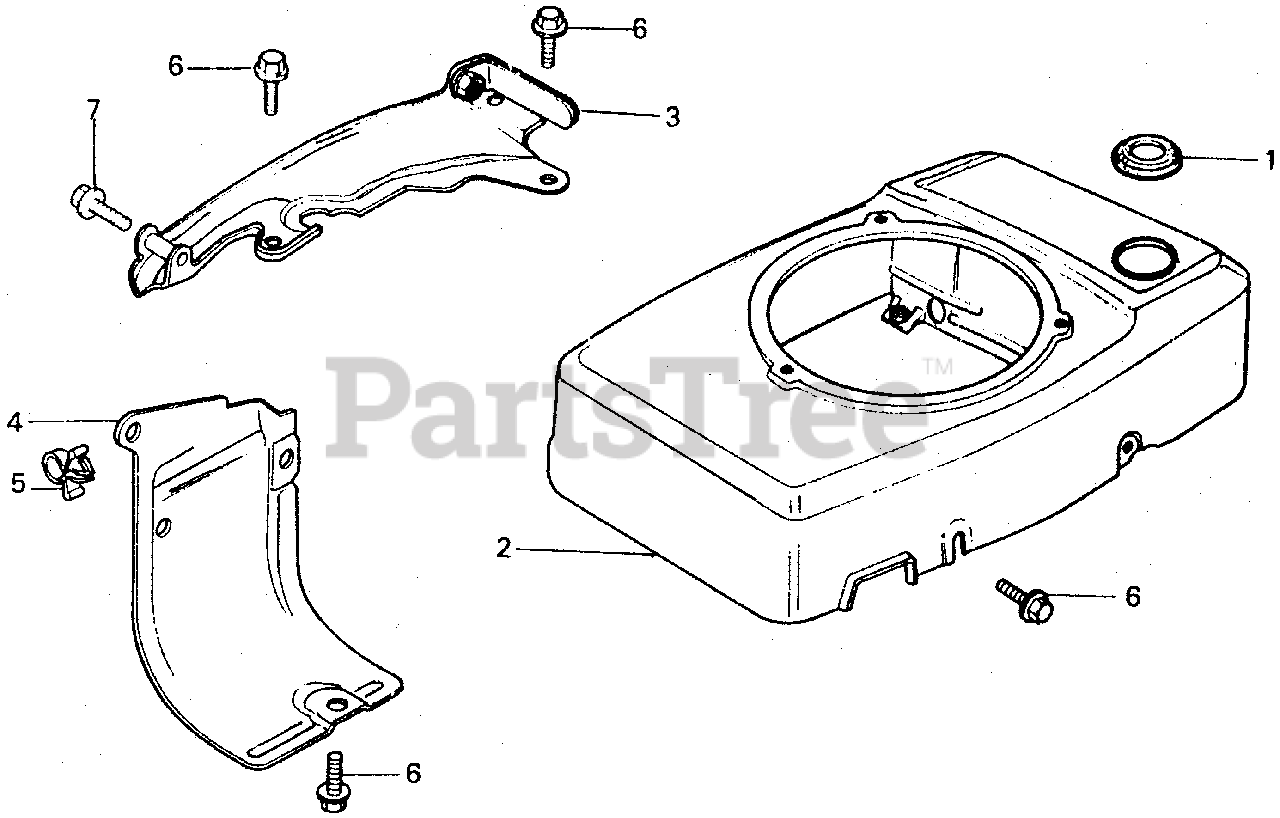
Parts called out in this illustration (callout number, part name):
1	SEAL, FILLER NECK
3	PLATE, SIDE
4	SHROUD
5	CLIP, IGNITION WIRE (8MM)
6	BOLT, FLANGE (6X12) (CT200)
7	BOLT, FLANGE (6X32)
